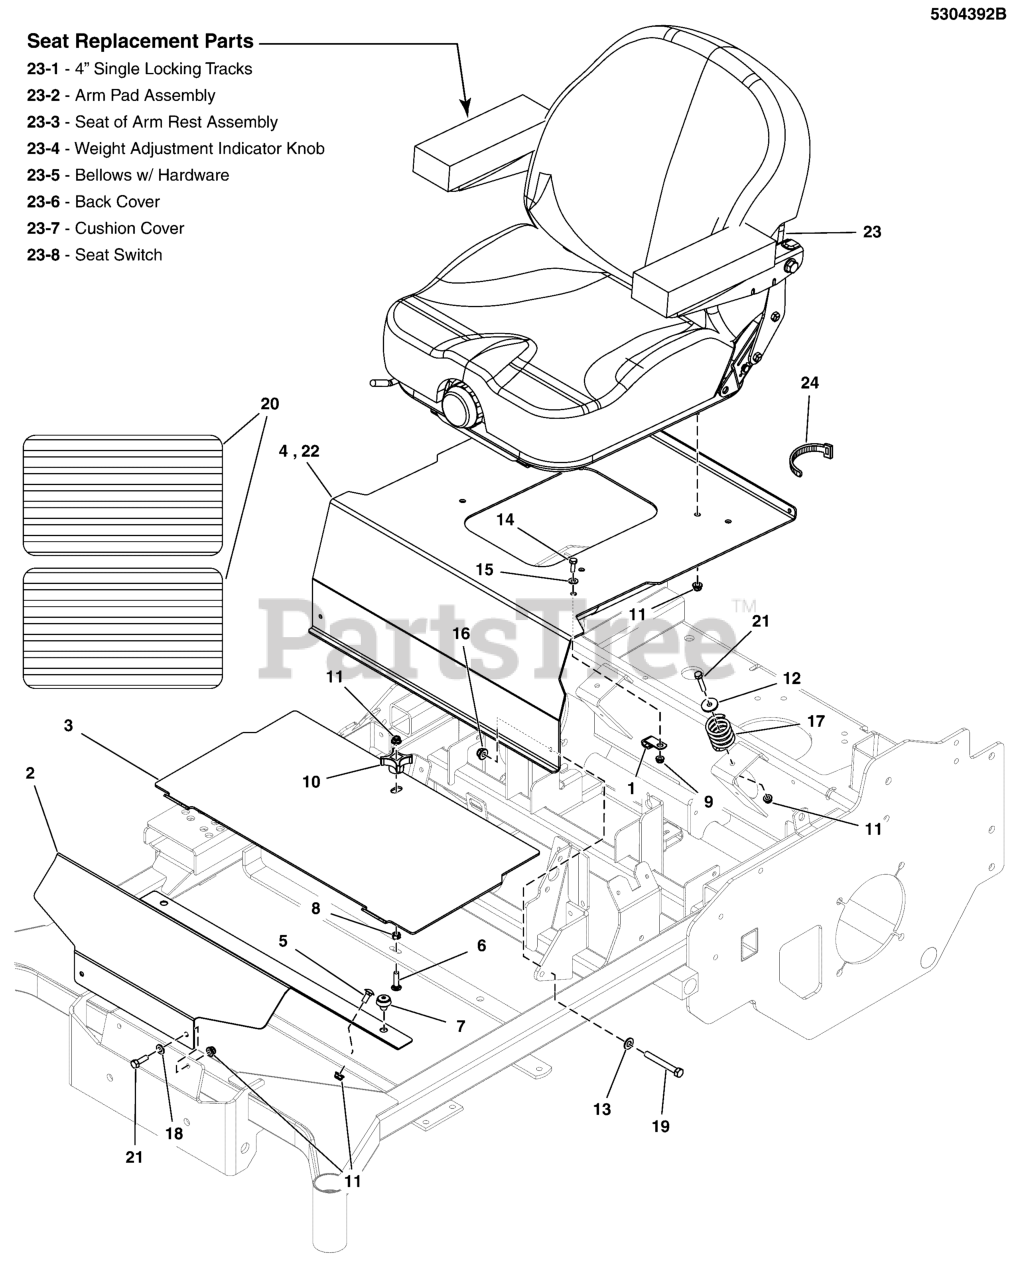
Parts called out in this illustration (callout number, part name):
1	CLAMP, 5/16", DOUBLE, WIRE & TUBE
2	PLATE, RIGID FLOOR, 200XT - RED
3	PLATE, REMOVABLE FLOOR, 200XT - RED
4	ASSM, SEAT PLATE W/DECAL - DOM (5415991B)
5	BOLT, 5/16-18 X 3/4, CARRIAGE, GD5, CZ
6	BOLT,5/16-18X1.500,CARRIAGE,SQ,GR5,ZC/CL
7	MNT, VBRTN, RBBR
8	NUT, 5/16-1/8, HEX, CNTR LK, ZINC PHOS/OIL
9	NUT, 1/4-20 Hex Nylock Flange
10	KNOB-INT THR .312-18 4-ARM 2.12WD 1.06LG
11	NUT, 5/16-18 HEX NYLOCK FLANGE NUT
12	WASHER, .34 X 1.25 X 10 GA
13	WASHER, 3/8 SAE
14	BOLT, 1/4"-20 X 3/4" GD5 YZ
15	WASHER, 1/4 SAE
16	NUT, 3/8 - 16 HEX NYLOCK FLANGE
17	SPRING, SEAT SUPPORT
18	WASHER, 5/16" SAE
19	BOLT, 3/8-16 X 3" GD5 CZ
20	SAFETY WALK, 10.00 X 19.00
21	BOLT, 5/16-18 X 1" GRD5 YZ
22	ASSM, SEAT PLATE W/DECAL - EXP (5415991B)
23	SEAT, MID BACK, SUSP SEAT'SINC, W/SWITCH
23-1	4" SINGLE LOCKING TRACKS BASE
23-2	ARM PAD ASSEMBLY BLK/CHAR CAR FIB/HARBR GRY RED WELT
23-3	SET OF ARMREST ASSEMBLY BLK/CHAR CAR FIB/HARBR GRY RED WELT
23-4	WEIGHT ADJUST INDICATOR KNOB ASSY BASE
23-5	BELLOWS W/ HARDWARE BASE
23-6	BACK COVER FOR FIXED BACK I3M BLK/CHAR CAR FIB/HARBR GRY RED WELT
23-7	CUSHION COVER FOR I3M BLK/CHAR CAR FIB/HARBR GRY RED WELT
23-8	SWITCH, SEAT
24	TIE, SELF-LOCKING, 6"
